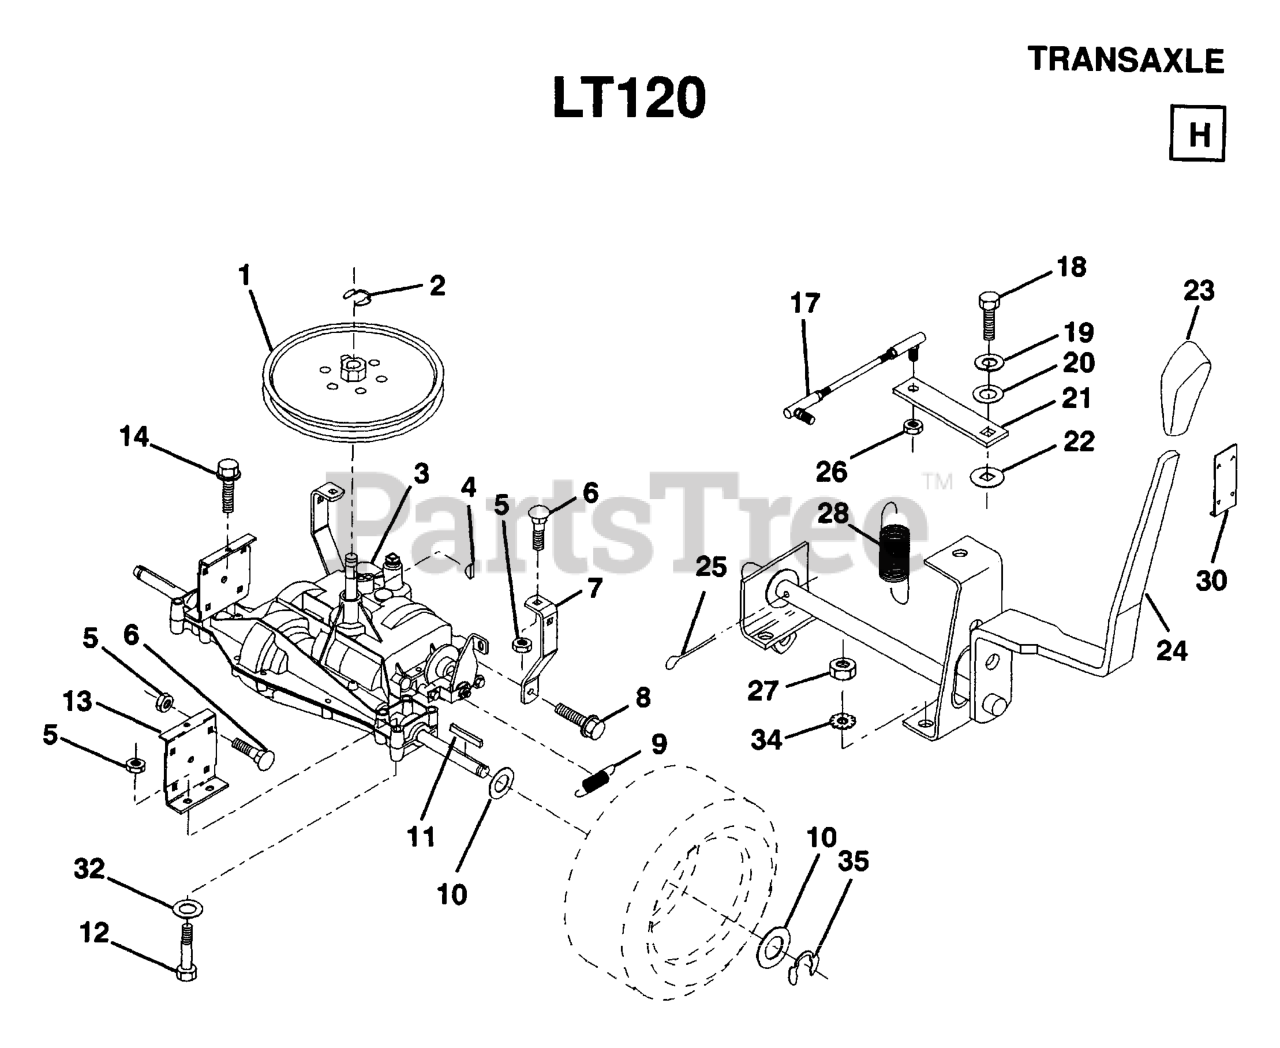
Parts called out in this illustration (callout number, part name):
2	RETAINING RING LT
3	Transaxle, Peerless 6 Speed Model Number 930-028
4	KEY STD (1373) DANA
5	LOCKNUT
6	RP BOLT 5/16-18 X3/4 ZN/YEL GR
7	STRAP,TORQUE
8	Screw 5/16-18 x 1/2 Hex, Self Tapping 5/16-18 x 1/2
9	SPRING T
11	SQUARE KEY
12	Bolt, Hex, Fin. 5/16 x 18 UNC x 2-1/2
13	BRKT,TRANSAXLE
14	SCREW.THDROL.5/16-18X3/4.TTY
18	BOLT LT
19	LOCKWASHER
20	WASHER LT
22	WASH-SHFT PLT LT
23	KNOB,SHT CONTROL
24	HANDLE ASSY SHIFT
25	PIN COTTER
26	LOCKNUT
27	NUT
28	SPRING.EXTENSION
30	KNOB RETAINER
32	WASHER
34	WASHER EXT TOOTH LOCK 5/16
